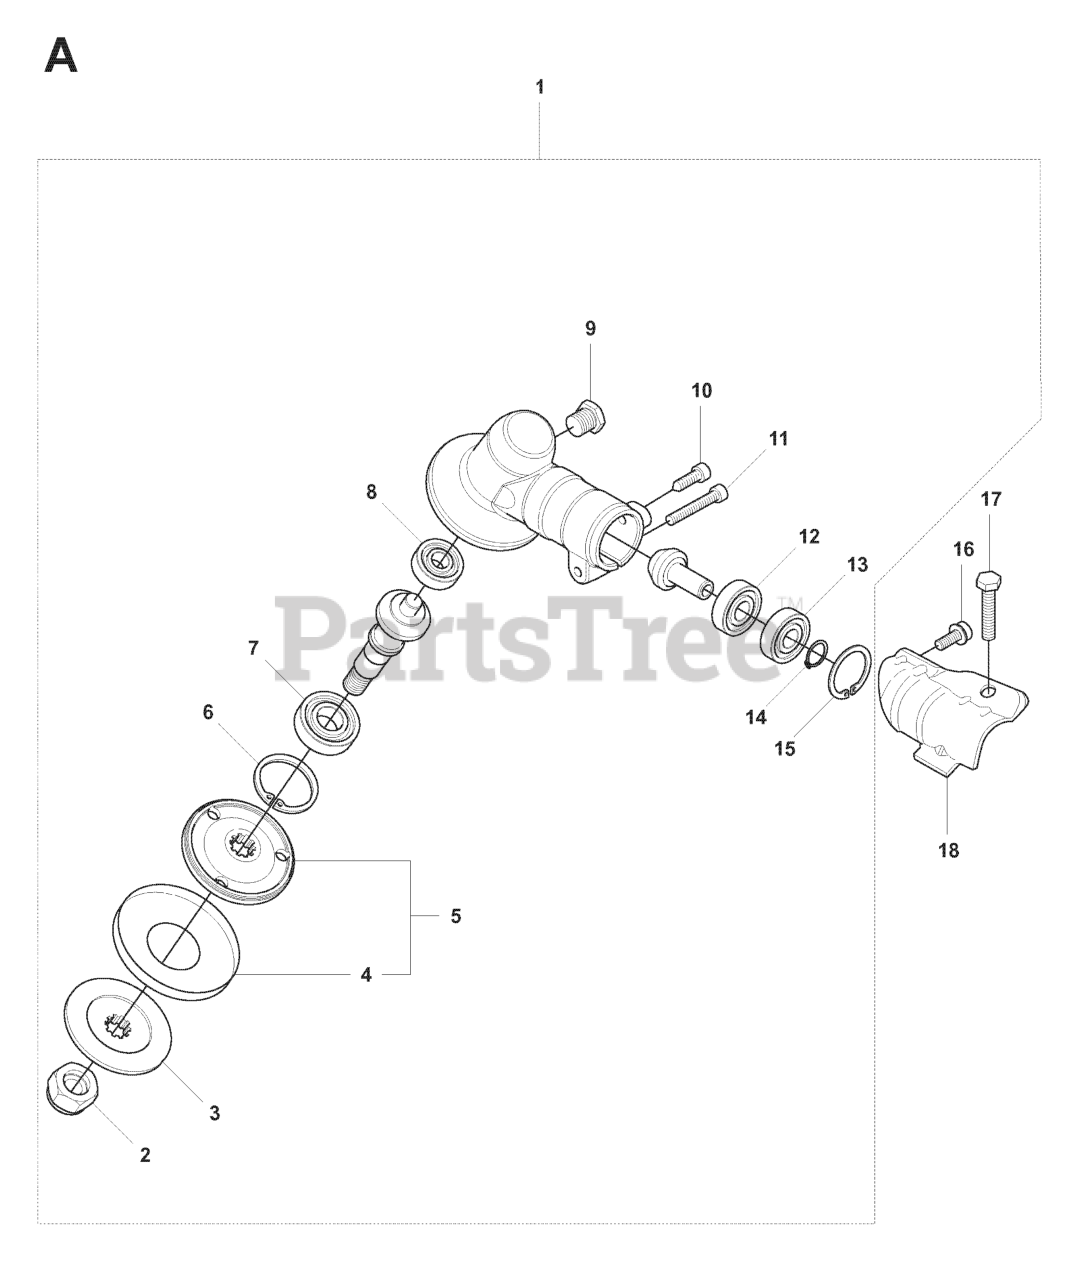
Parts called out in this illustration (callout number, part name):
1	GEAR HEAD
2	GEARHEAD NUT - BRUSHCUTTER
3	SUPPORT FLANGE
4	WASHER
5	DRIVE DISC
6	RETAINING RING SGH 28
7	BEARING
8	BALL BEARING 8X22X7/608Z
12	BALL BEARING 24X9X1/609ZR
14	RETAINING RING
15	RETAINING RING
17	SCREW M6S 6X20
18	RP BRACKET TRIMMER GUARD
